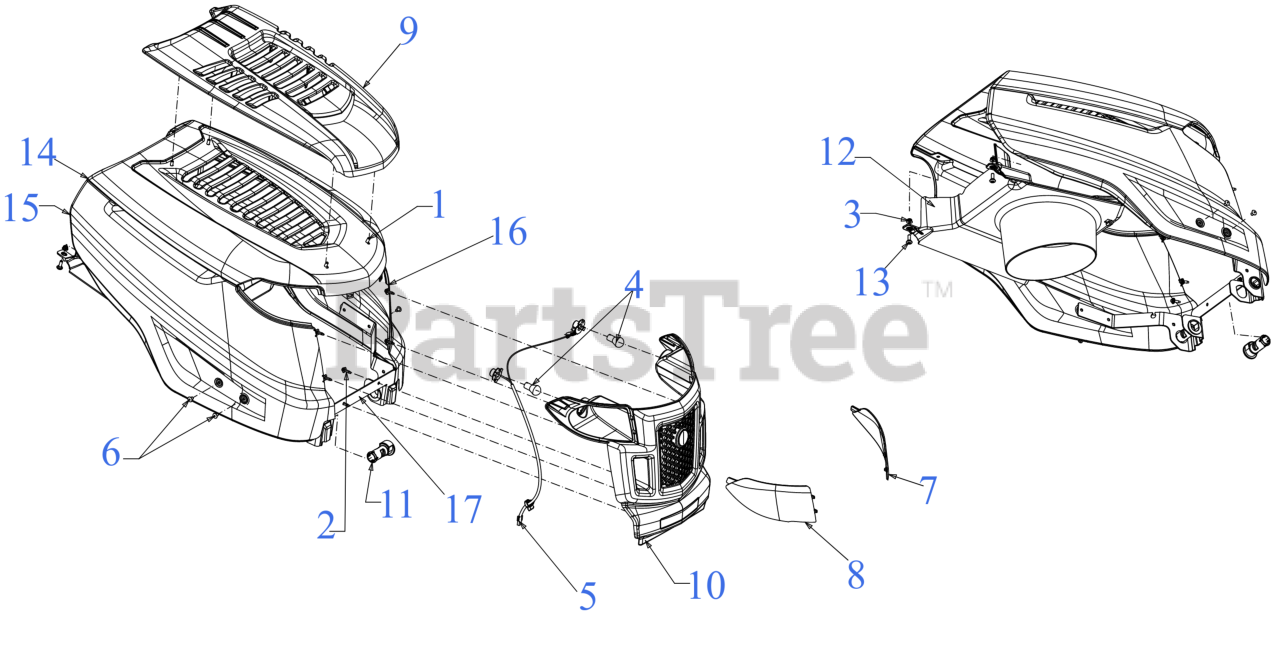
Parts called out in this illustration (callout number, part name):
1	HEX SCREW 1/4-15 x .50
2	SCREW 1/4-10 x .750
3	FLANGE LOCK NUT
4	MINIATURE LAMP-12V #1156
5	HEADLIGHT HARNESS
6	POP RIVET 6.4MM x 10MM
7	LENS (LH)
8	LENS (RH)
9	HOOD SCOOP
10	GRILLE(K STYLE) NON T-BILT
11	HOOD PIVOT PIN
12	HOOD PLENUM (K STYLE)
13	SCREW-SHLDR 1/4-20 x .75 TORX
